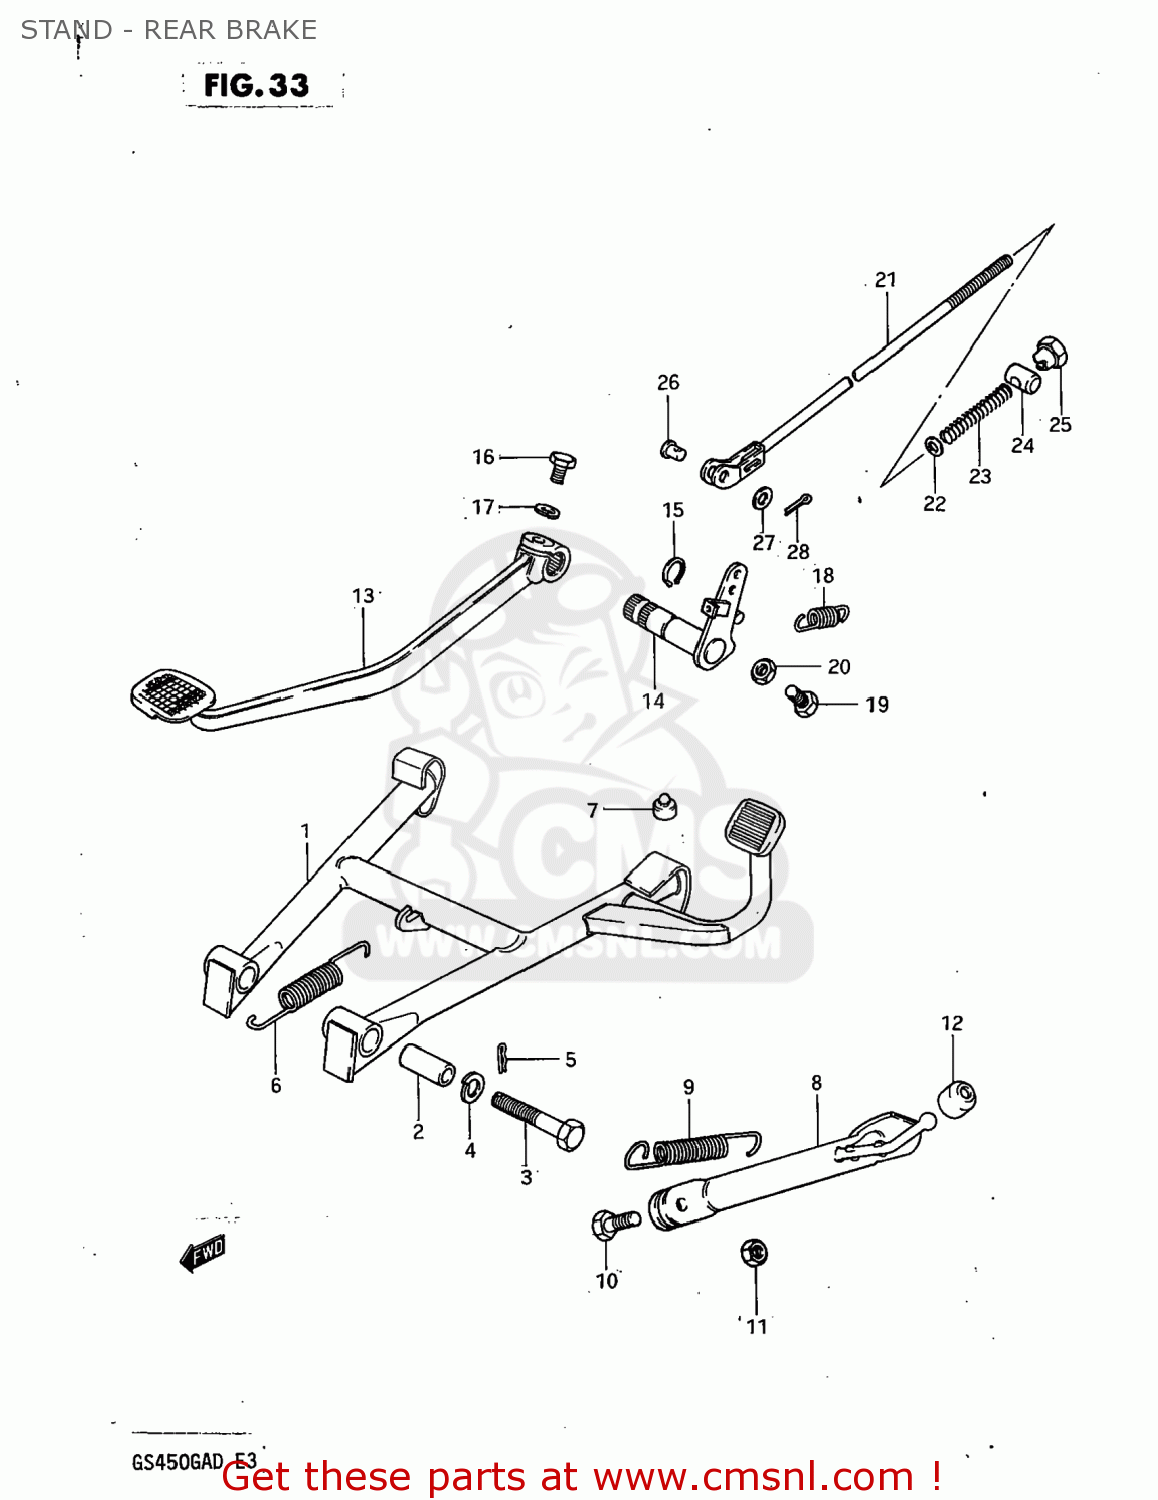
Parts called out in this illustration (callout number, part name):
1	STAND,CENTER
2	SPACER(10X16X38.8)
3	BOLT
4	LOCK WASHER
5	CLIP
6	SPRING
7	CUSHION
8	STAND,SIDE
9	SPRING
10	BOLT(10X30)
11	NUT
12	CUSHION
13	PEDAL,BRAKE
14	ARM,BRAKE PEDAL
15	CIRCLIP
16	BOLT
17	LOCK WASHER
18	SPRING
19	BOLT
20	NUT
21	ROD ASSEMBLY,REAR BRAKE
22	WASHER
23	SPRING
24	PIN
25	NUT
26	PIN(L:13.5)
27	WASHER
28	PIN 20X20
